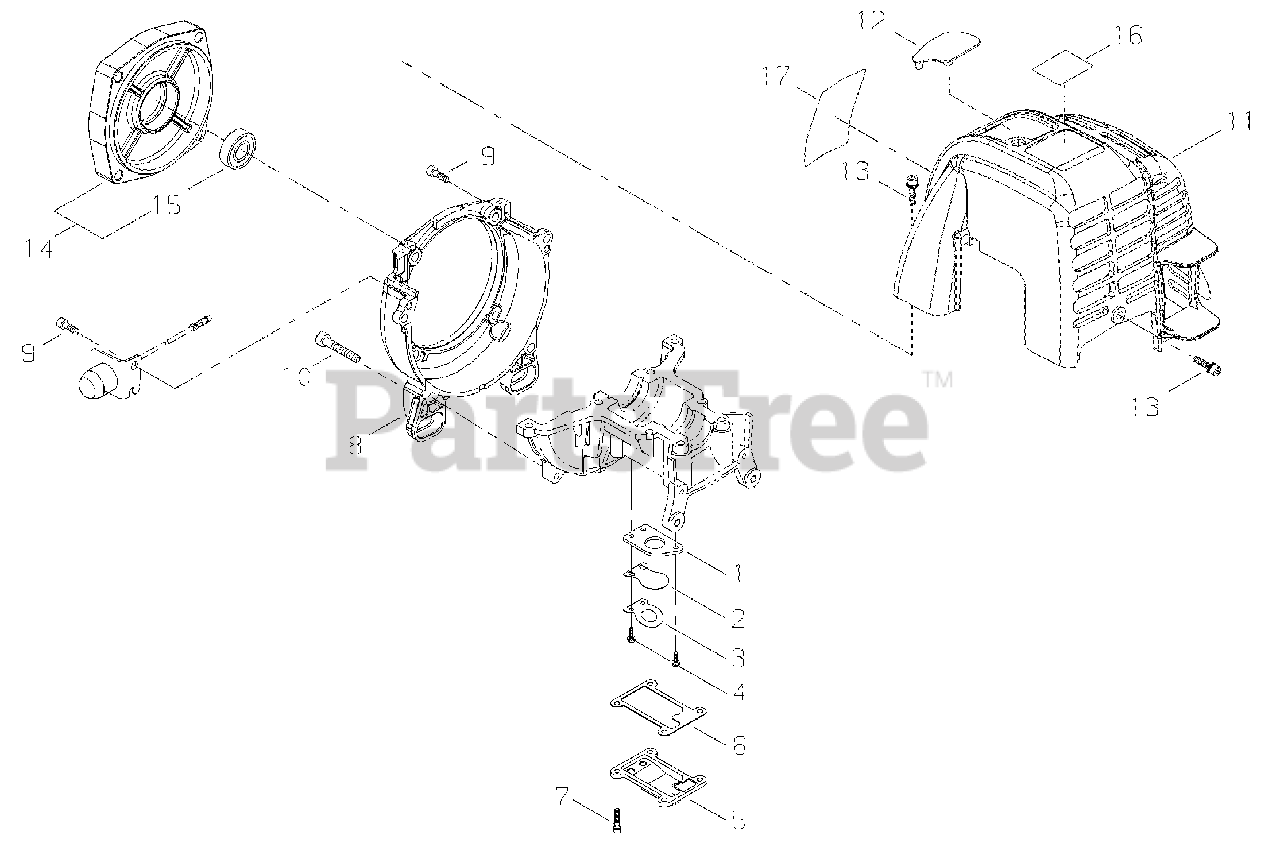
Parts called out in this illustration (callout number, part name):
1	PLATE, REED BACKING
2	VALVE, REED
3	STOP, REED VALVE
4	SCREW M3×10
5	COVER, REED VALVE
6	GASKET, REED VALVE
7	BOLT M4×14
8	COVER, FAN
9	BOLT 5×16
10	BOLT 5×30
11	COVER, ENGINE
12	COVER, SPARK PLUG
13	BOLT M4×14
14	ADAPTOR SET, PUMP
15	BEARING, BALL 6002
16	LABEL, GP3410
17	LABEL, C4 SHINDAIWA
